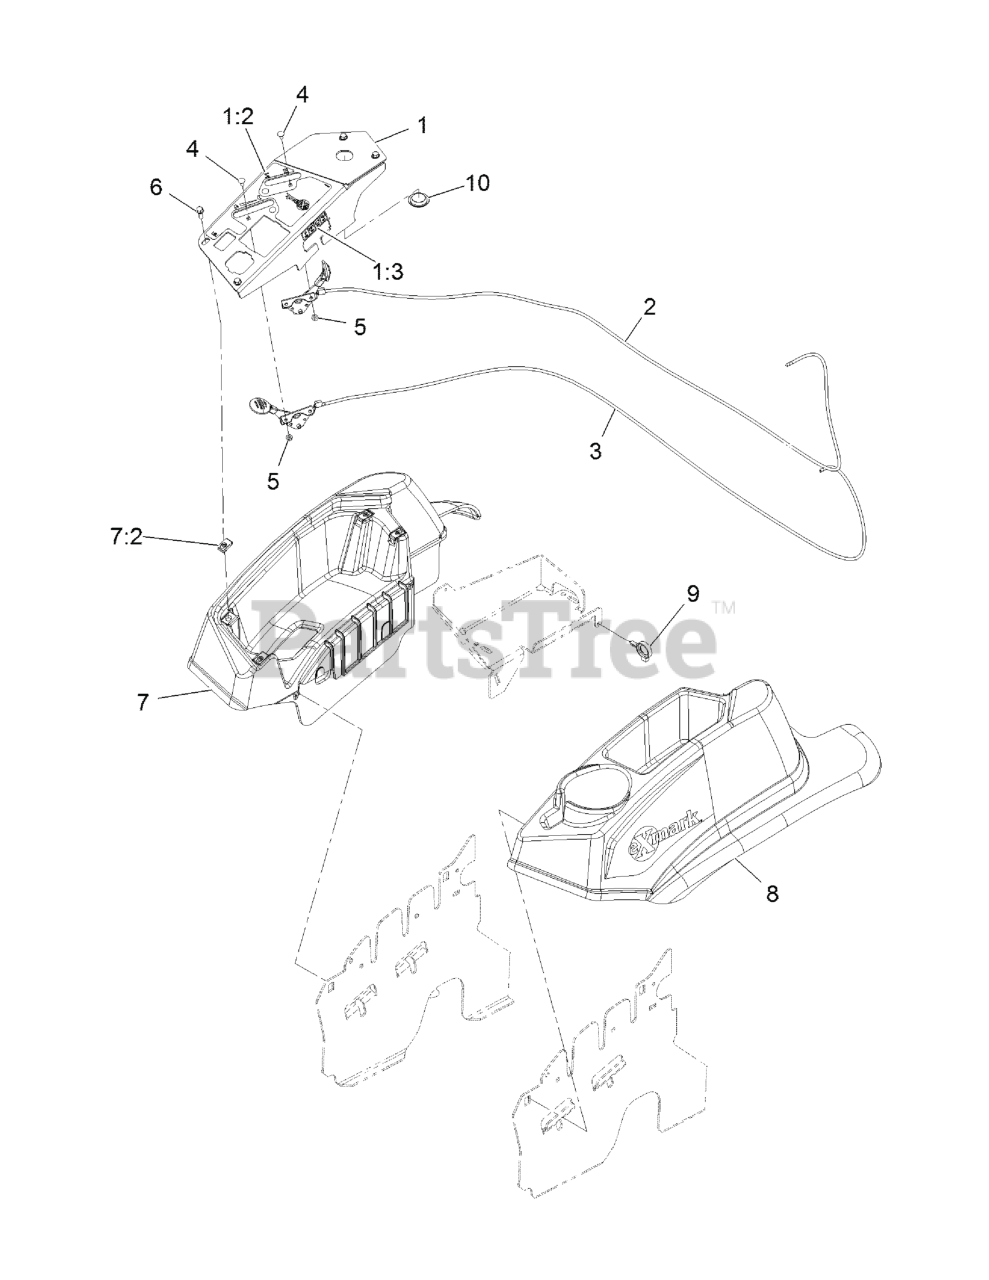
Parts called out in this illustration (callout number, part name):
1	CONSOLE,PANEL W/DECAL
1:2	DECAL-CONTROL PANEL NON-E
1:3	DECAL-FUSES
2	ASM, CHOKE CABLE
3	ASM,THROTTLE CABLE
4	BOLT-CARR
5	NUT-LOCK, NI
6	SCREW-HWH
7	CONSOLE,RH AS ASM
8	CONSOLE, LH AS
9	CLAMP-HOSE
10	PLUG-PLASTIC
